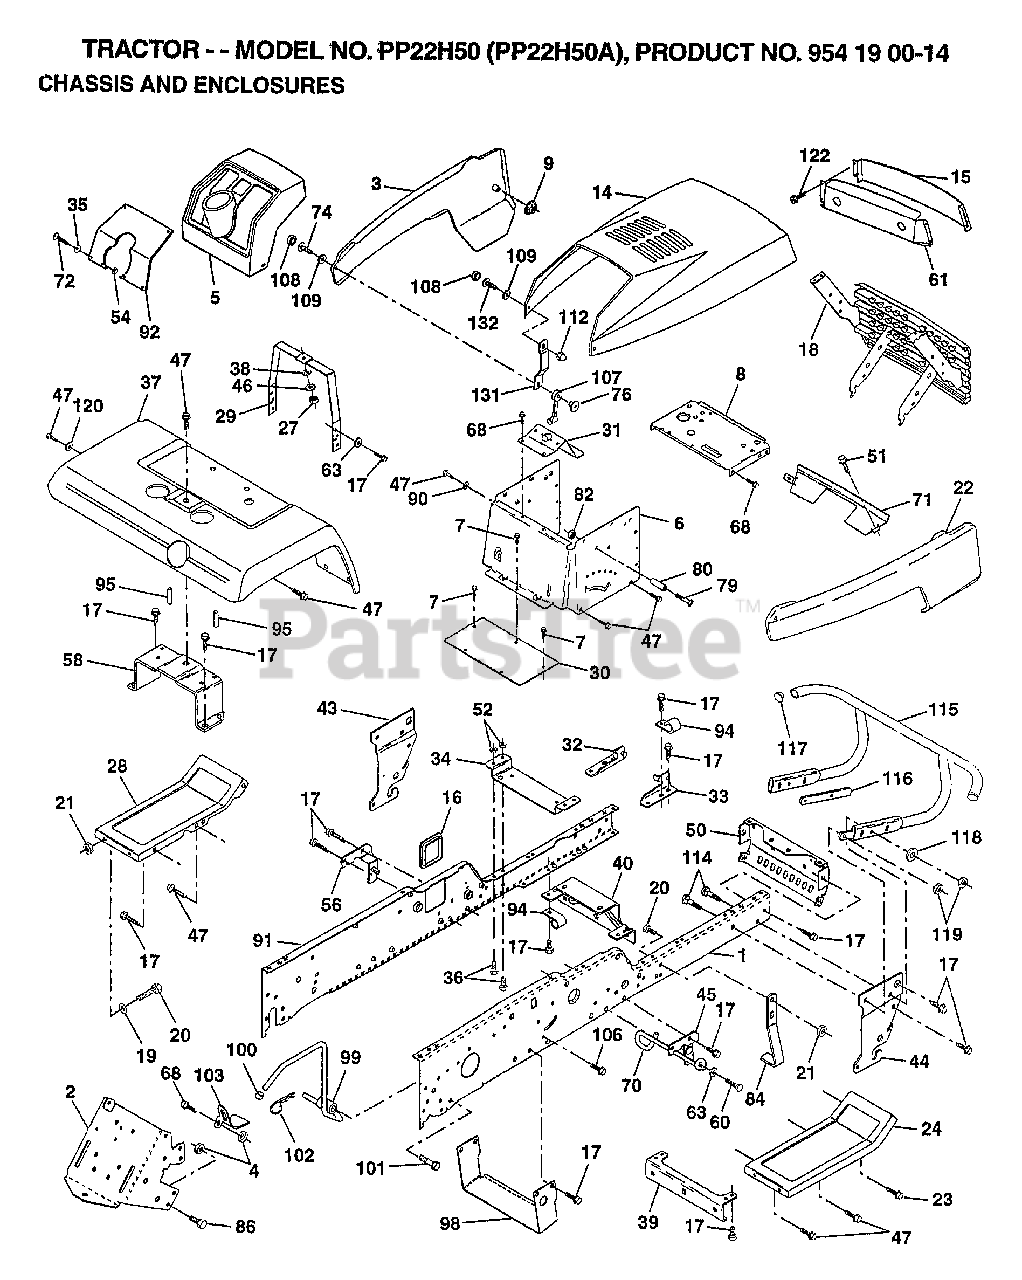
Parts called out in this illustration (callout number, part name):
1	"RAIL,FRAME RH"
2	DRAWBAR GT
3	"PANEL ASM-SIDE,LH"
4	NUT.7/16
5	DASHBOARD BLACK
6	DASH LOWER
7	SCREW
8	SUPPORT.DASH.BTRY
9	PAL NUT LT
14	"HOOD, YARD PRO"
15	LENS.BAR.CLEAR
16	COVER ACCESS
17	SCREW
19	WASHER
20	BOLT
22	"PANEL ASM SIDE,RH"
23	SCREW GTV
24	FOOTREST.RH.LT/GT
28	FOOTREST.LH.LT/GT
29	DASH.SUPT.YP/HUSQ
30	SADDLE.HYDRO.95
31	BRAKET.SUPT.STEER
32	BRACKET ASM FRAME
33	BRACKET ASM FRAME
34	BRACKET.ENG.SUPT.
35	WASHER
36	BOLT
38	LOCKWASHER
39	BRACKET.AXLE.FRT.
40	"BRKT SUPPORT,AXLE"
43	BRACKET.SUS.FT.LH
44	BRACKET.SUS.FT.RH
45	BRACKET.SUSP.RH.
46	WASHER PM
47	SCREW LT
50	"BRKT CHASSIS,FRNT"
51	SCREW CRT
52	NUT CROWN LOCK
56	BRACKET.SUSP.LH.
58	BRKT.ASM.FENDER
60	SCREW
61	BEZEL.ASM.
63	WASHER
68	SCREW LT
70	GUIDE.BELT.MID.SP
72	SCREW
74	SCREW
76	WELDNUT
79	SCREW
80	SPACER LT
84	STOP.OVER.CENTER
86	BOLT
90	LOCKWASHER
91	"RAIL FRAME,LH"
92	PLATE, SILKSCREEN DASH
94	CLIP GTV
95	NUT-PUSH YT
98	BRACKET SKID CHAS
99	ROD BYPASS
101	SCREW LT
102	RETAINER M
103	LOCK BYPASS BRKT
107	HOOD LATCH T
108	SNAP CAP LT
109	WASHER LT
112	ACORN NUT RB
114	BOLT.3/8-14X1.25
115	BUMPER.ASM
116	BRACKET.EXT.BUMP.
117	PLUG.PLASTIC
118	WASHER
120	WASHER HYT
131	BKT.SPT.HOOD/PANL
132	SCREW.10-24X3/8.
